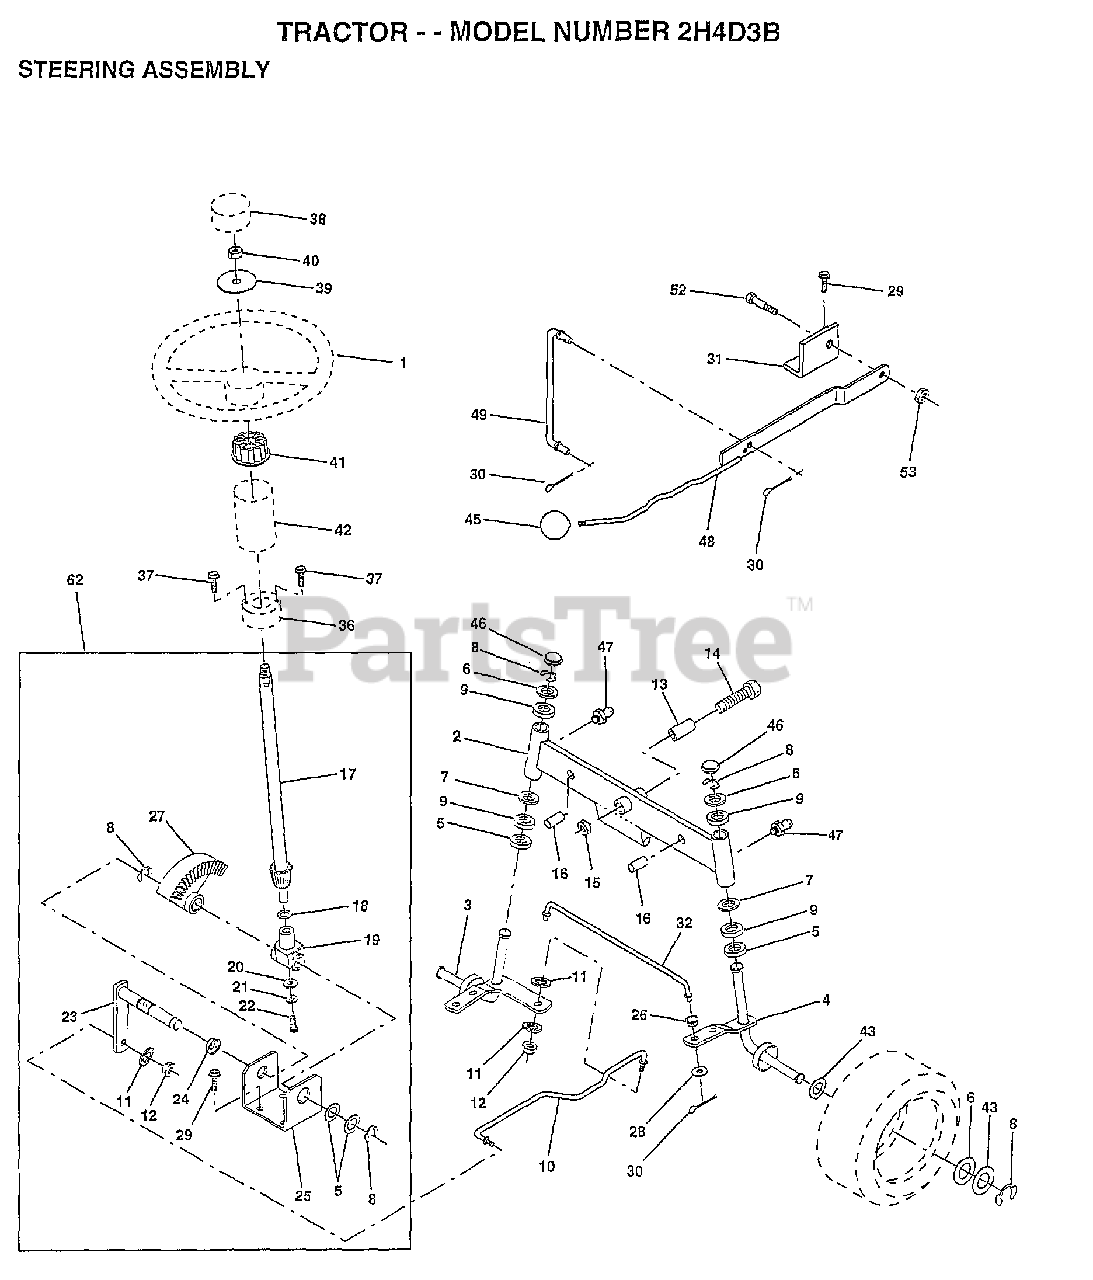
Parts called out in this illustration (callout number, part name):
2	AXLE ASM FRONT
3	SPINDLE LH
4	SPINDLE RH
5	WASHER .T
6	WASHER
7	WASHER
8	RING
9	COL. SRTG. BEAR.
11	LOCKWASHER
13	BEARING
14	BOLT HEX 5/8-11
15	"NUT-LOC,FLANGE LT"
16	AXLE PIN
17	STEERING SHAFT
18	THRUST WASHER
19	SUPPORT.SHAFT
21	LOCKWASHER
22	SCREW.SCKTHD.CAP
24	NYLINER T
25	"BRKT,STEERING"
26	BUSHING.DRAGLINK
27	GEAR SECTOR
28	WASHER
29	SCREW
30	COTTER PIN
31	BRKT.PVT.MAN.LVR.
32	TIE ROD
36	BUSHING.STRG.3/4
37	SCREW.10-24X1/2
38	ST WHL INSERT CAP
39	WASHER
41	ADAPTER LT
42	BOOT SHAFT STEER
43	WASHER
45	KNOB T (1/2-HOLE)
46	CAP
47	ZERK M
48	LEVER.ASM.CLUTCH
49	LINK CLTCH W/NUTS
52	"BOLT, SHOULDER LT"
